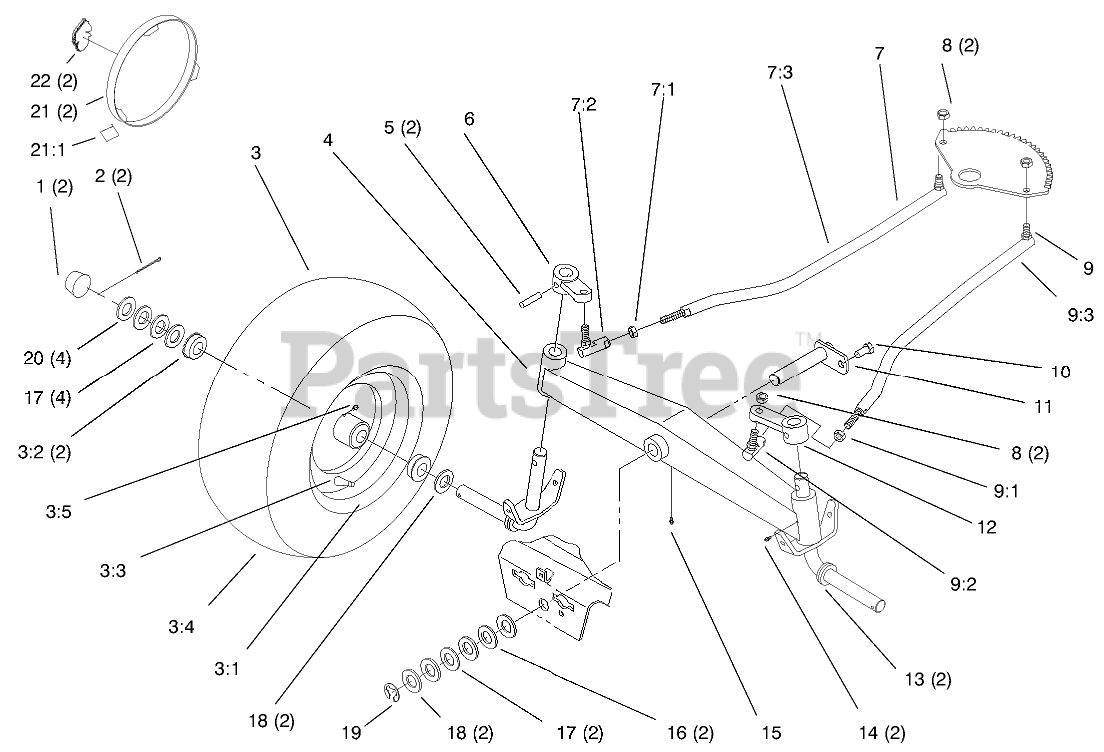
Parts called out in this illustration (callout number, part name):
1	CAP-HUB
2	PIN-COTTER
3	ASM-Wheel & Tire
3:1	Wheel ASM
3:2	BEARING-WHEEL
3:3	VALVE
3:4	Tire (16 x 6.5-8) 2-Ply -2 Wheel Axel
3:5	ZERK-GREASE
4	AXLE-FRONT
6	Arm-Front Spindle
7	LINKAGE-STEERING, RH
7:1	Nut-Hex Jam
7:2	BALL-JOINT
7:3	Ball Link ASM
9	LINKAGE-STEERING, LH
9:1	Nut-Hex Jam
9:2	BALL-JOINT
9:3	Ball Link ASM
10	SCREW-HWH, TAPTITE
11	PIN-AXLE
12	Arm-Front Spindle
13	SPINDLE
14	FITTING-GREASE
15	FITTING-LUBE, 45 DEG
16	Washer
17	WASHER
18	WASHER-SHIM
19	E-RING
20	WASHER-PLAIN
21	SILVER HUB CAP/LOGO ASM
21	HUBCAP - 8"
22	LOGO - HORSEHEAD
